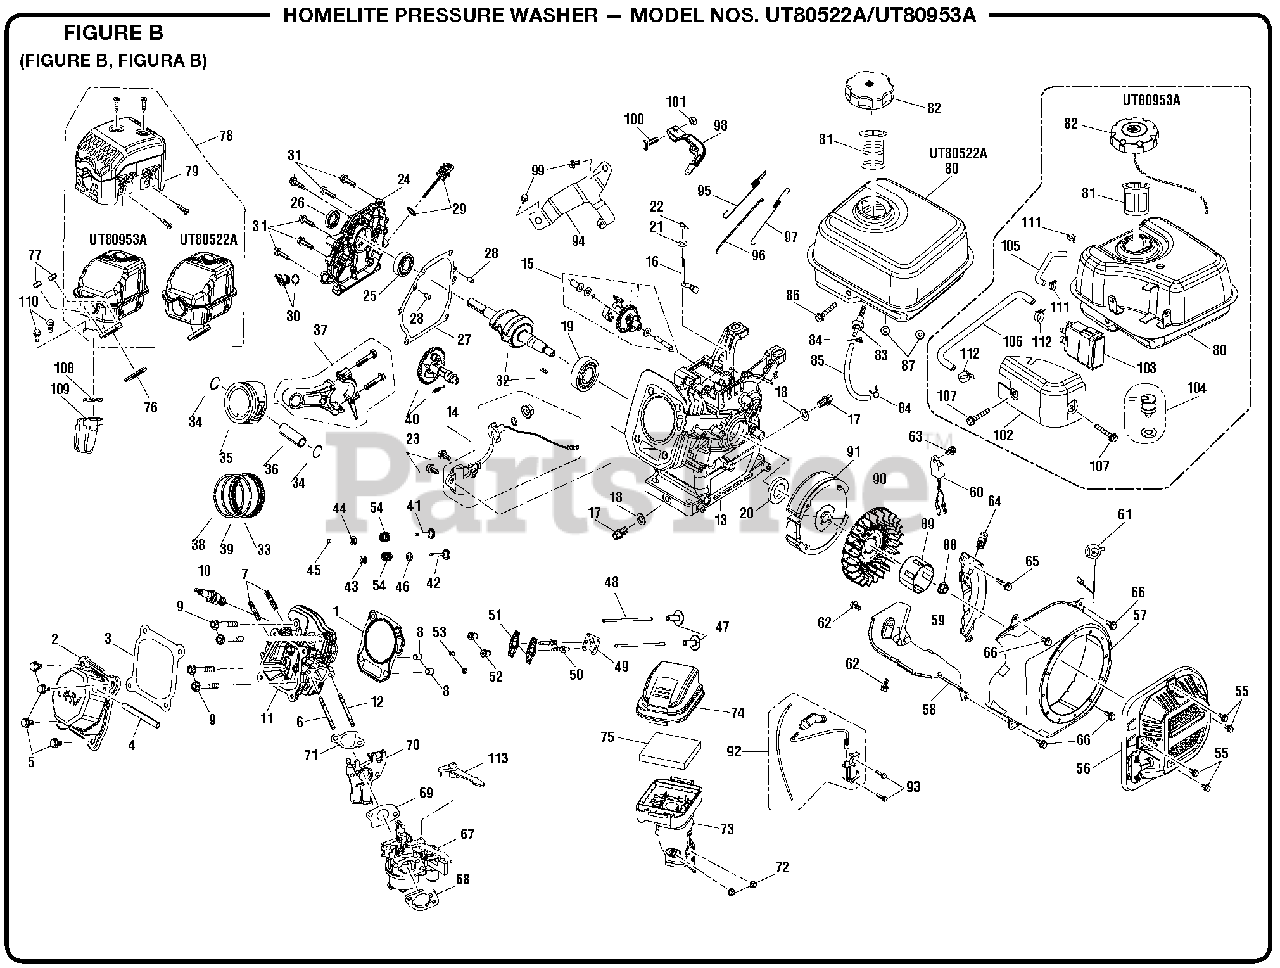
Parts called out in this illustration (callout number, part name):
1	Cylinder Head Gasket
2	Cylinder Head Cover Assembly
3	Cylinder Head Cover Gasket
4	Breather Tube
9	Cylinder Head Bolt
10	Spark Plug (Champion RC12YC)
11	Cylinder Head Assembly
13	Crankcase Assembly
14	Engine Oil Sensor
15	Governor Gear Assembly
16	Governor Arm
17	Drain Plug Bolt
21	Governor Gear Washer
24	Crankcase Cover Assembly
27	Crankcase Gasket
29	Oil Dipstick Assembly
30	Engine Oil Plug Assembly
32	Crankshaft Assembly
33	Oil Ring Set
34	Piston Pin Clip
35	Piston Assembly
37	Connecting Rod
39	Second Ring
40	Camshaft Assembly
41	Exhaust Valve
42	Intake Valve
43	Valve Spring Seat
44	Exhaust Valve Retainer
45	Valve Rotator
47	Valve Tappet
48	Valve Lifter
49	Lifter Stopper Plate Assembly
50	Valve Adjusting Bolt
51	Valve Rocker
52	Valve Adjusting Nut
53	Valve Lock Nut
54	Valve Spring
55	Bolt
56	Recoil Starter Assembly
58	Cylinder Body Shroud
59	Lower Shield
60	Oil Protector
61	Stop Engine Switch Assembly
67	Carburetor Assembly
68	Air Cleaner Gasket
69	Carburetor Gasket
70	Carburetor Insulator Plate
71	Carburetor Insulator Gasket
73	Air Cleaner
74	Air Cleaner Case Cover
75	Air Cleaner Element
76	Exhaust Outlet Gasket
78	Muffler Assembly
79	Muffler Outer Cover
80	Fuel Tank
81	Fuel Strainer
82	Fuel Tank Cap
83	Fuel Tank Outlet Assembly
89	Starter Pulley
91	Flywheel Assembly
92	Ignition Coil
94	Throttle Control Assembly
95	Governor Spring
96	Governor Rod
97	Throttle Valve Return Spring
98	Governor Support Assembly
100	Governor Support Bolt
102	Canister Cover
103	Carbon Canister
104	Rollover Valve
105	Vapor Line
106	Vapor Line
107	Bolt
108	Air Valve Gasket
109	Muffler Air Valve
110	Bolt
111	Clamp
112	Clamp
113	Choke Lever
